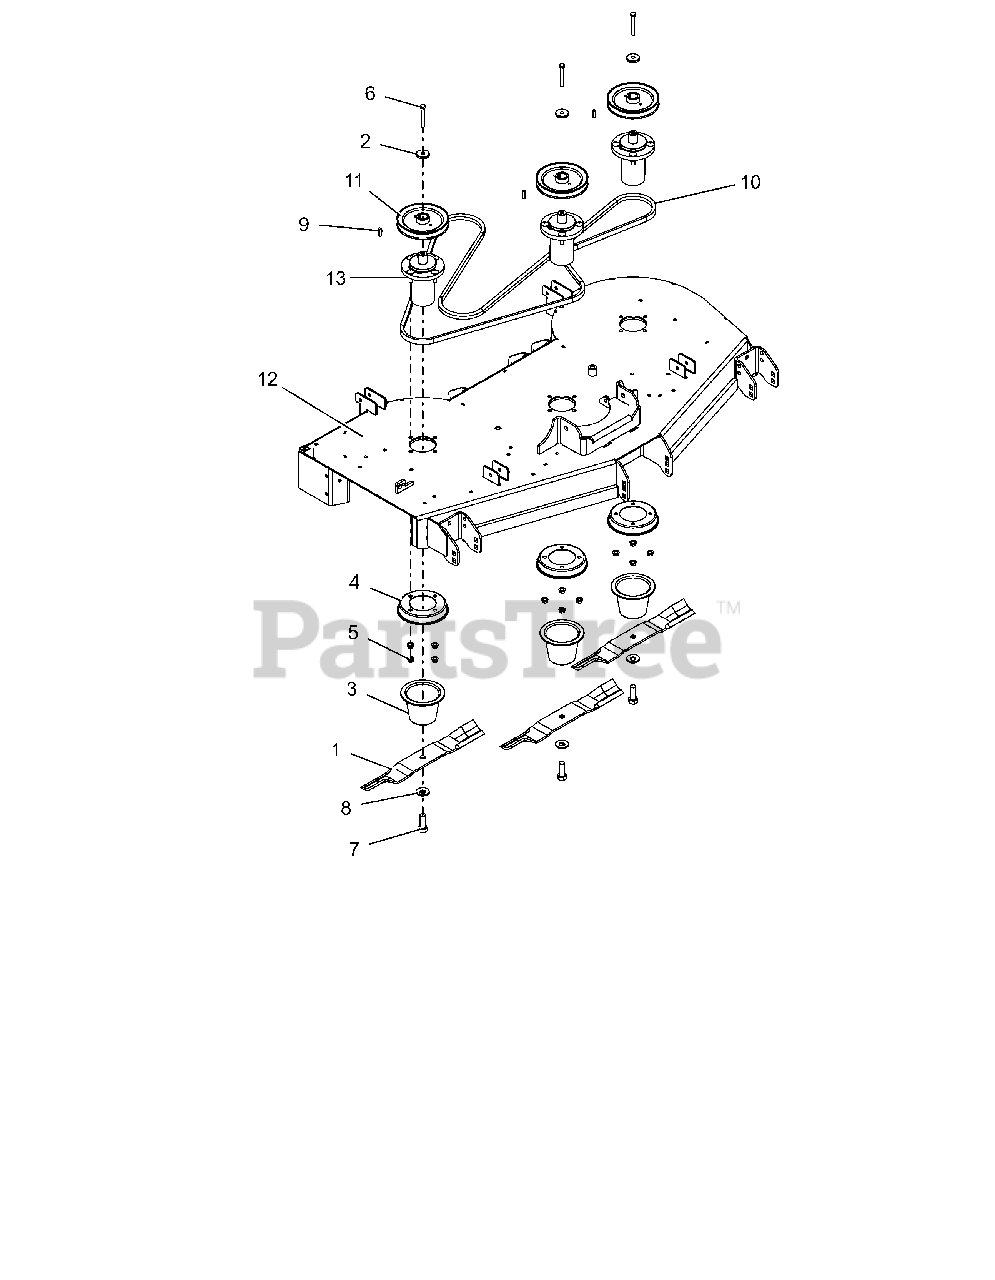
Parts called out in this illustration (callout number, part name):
1	BLADE, 18.00" MOWER (HI-LIFT)
2	RETAINER, SHEAVE
3	GUARD, SPINDLE LOWER
4	GUARD, SPINDLE TOP
5	NUT-LK-CTR-FLG .38-16 YWZC
6	BLT-HEX .38-16X2.75 GR8 YWZC
7	BLT-HEX .62-18X1.75 GR8 YWZC
8	WSHR-BLVL .669X1.535X.138
9	KEY, SQ .25X.25X1.00 RC 40-50
10	BELT, B-SECTION EPDM RAW EDGE
11	PULLEY, 1.00 ID X 6.00 OD
12	KIT, 52" MOWER DECK W DECALS
13	ASM, MAINT FREE ALUM SPINDLE
